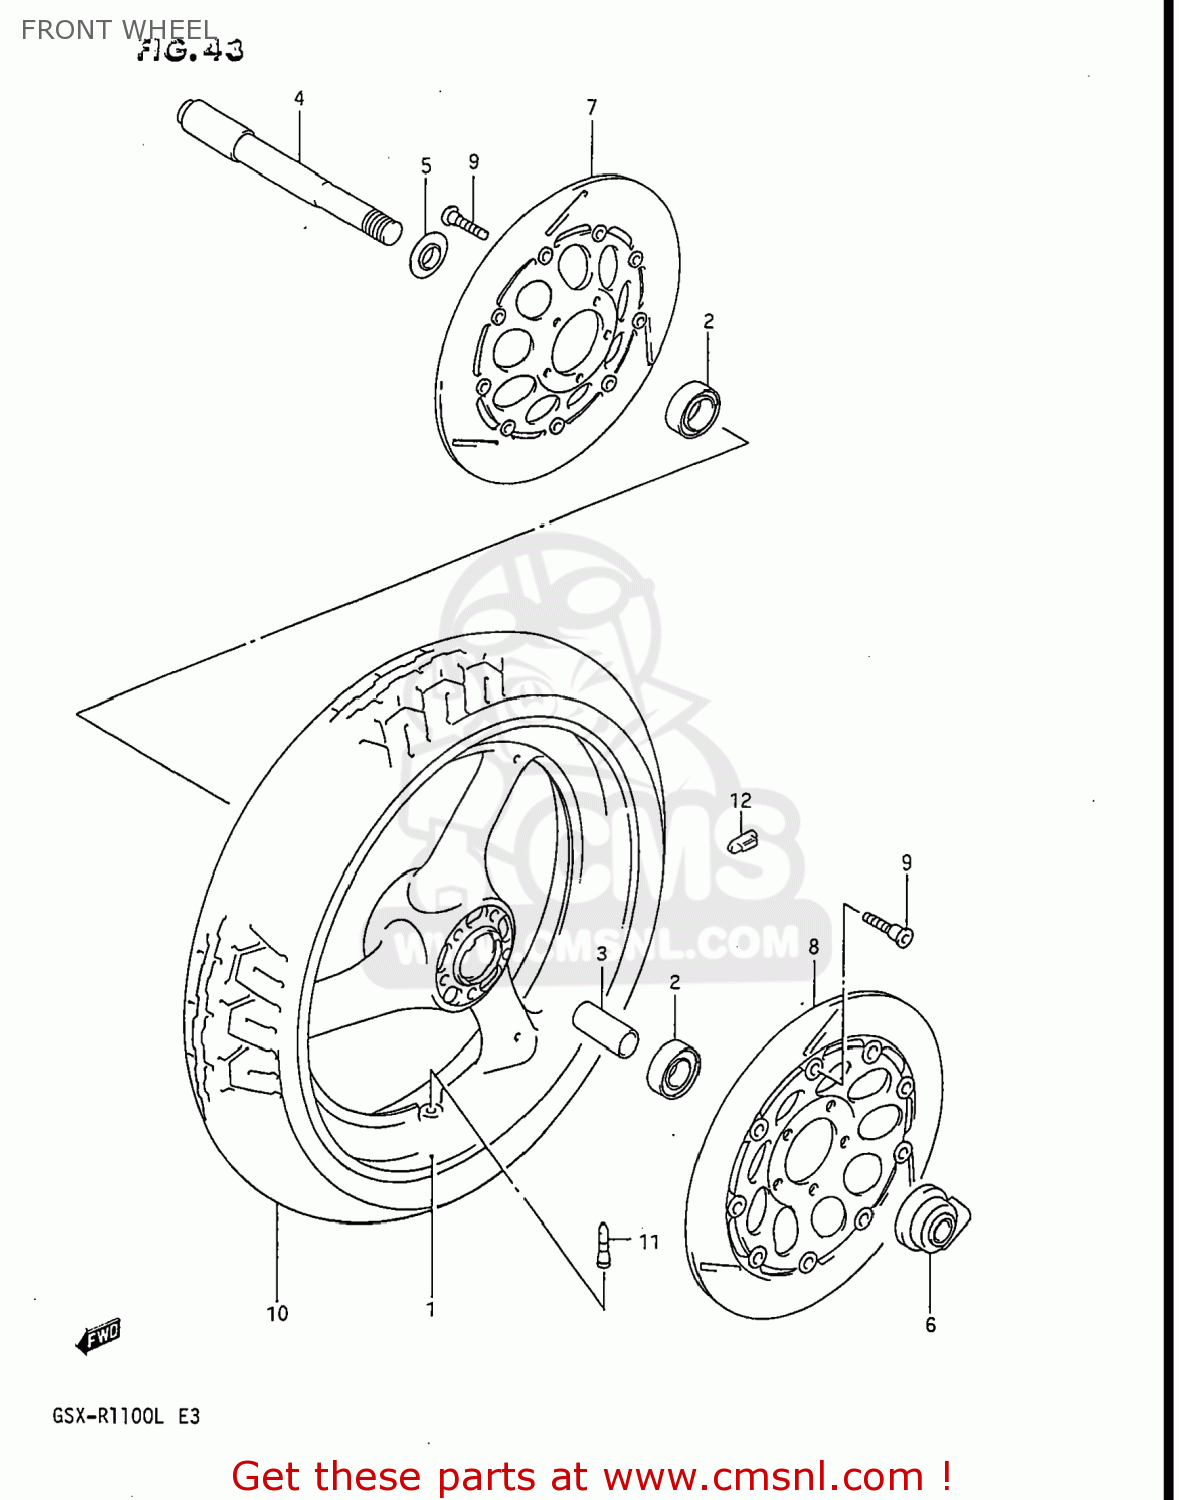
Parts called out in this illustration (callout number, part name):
1	WHEEL,FRONT
2	BEARING
3	SPACER(20.8X27.2X74)
4	AXLE,FR
5	SPACER,FR HUB BEARING,R
6	BOX ASSEMBLY,SPEEDOMETER GEAR
7	DISC,BRAKE
8	DISC,BRAKE
9	BOLT
10	TIRE,FRONT
11	VALVE ASSY,WHEEL RIM(TR412)
12	BALANCER,WHEEL
